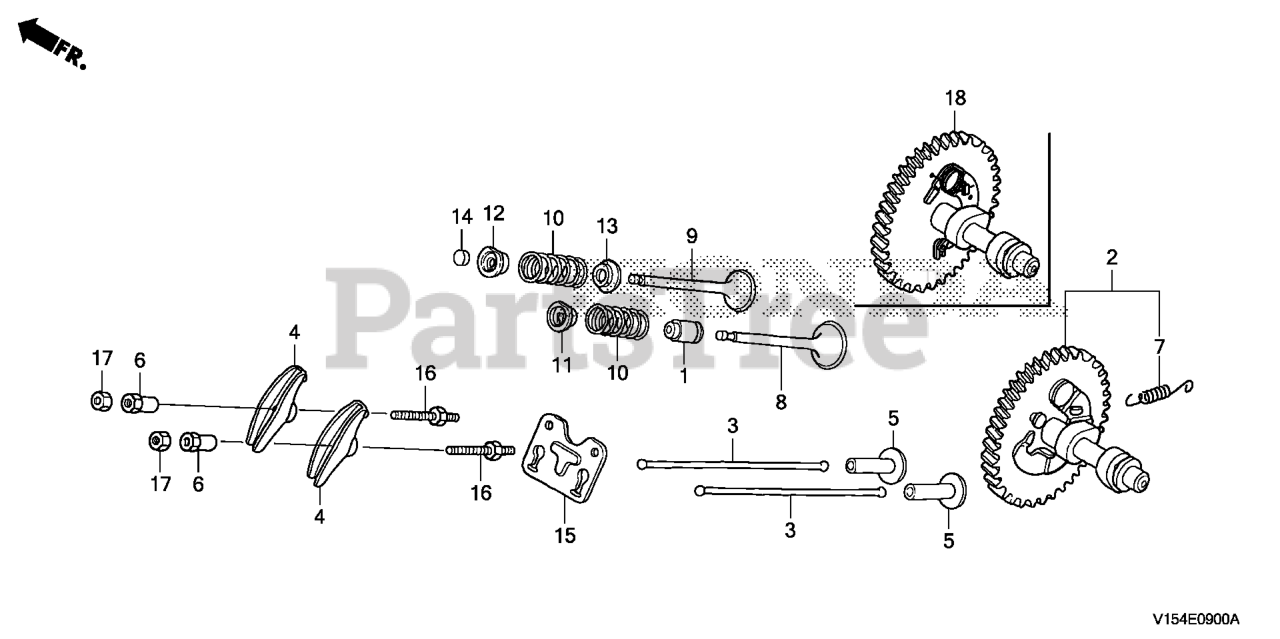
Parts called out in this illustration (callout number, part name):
1	SEAL, VALVE STEM
4	ARM, VALVE ROCKER
5	LIFTER, VALVE
6	PIVOT, ROCKER ARM
8	VALVE, IN.
9	VALVE, EX.
10	SPRING, VALVE
11	RETAINER, IN. VALVE SPRING (EXHAUST SIDE)
12	RETAINER, IN. VALVE SPRING (EXHAUST SIDE)
13	SEAT, VALVE SPRING
15	GUIDE, PUSH ROD
16	BOLT, PIVOT (8MM)
17	NUT, PIVOT ADJ.
18	CAMSHAFT COMP (STD)
